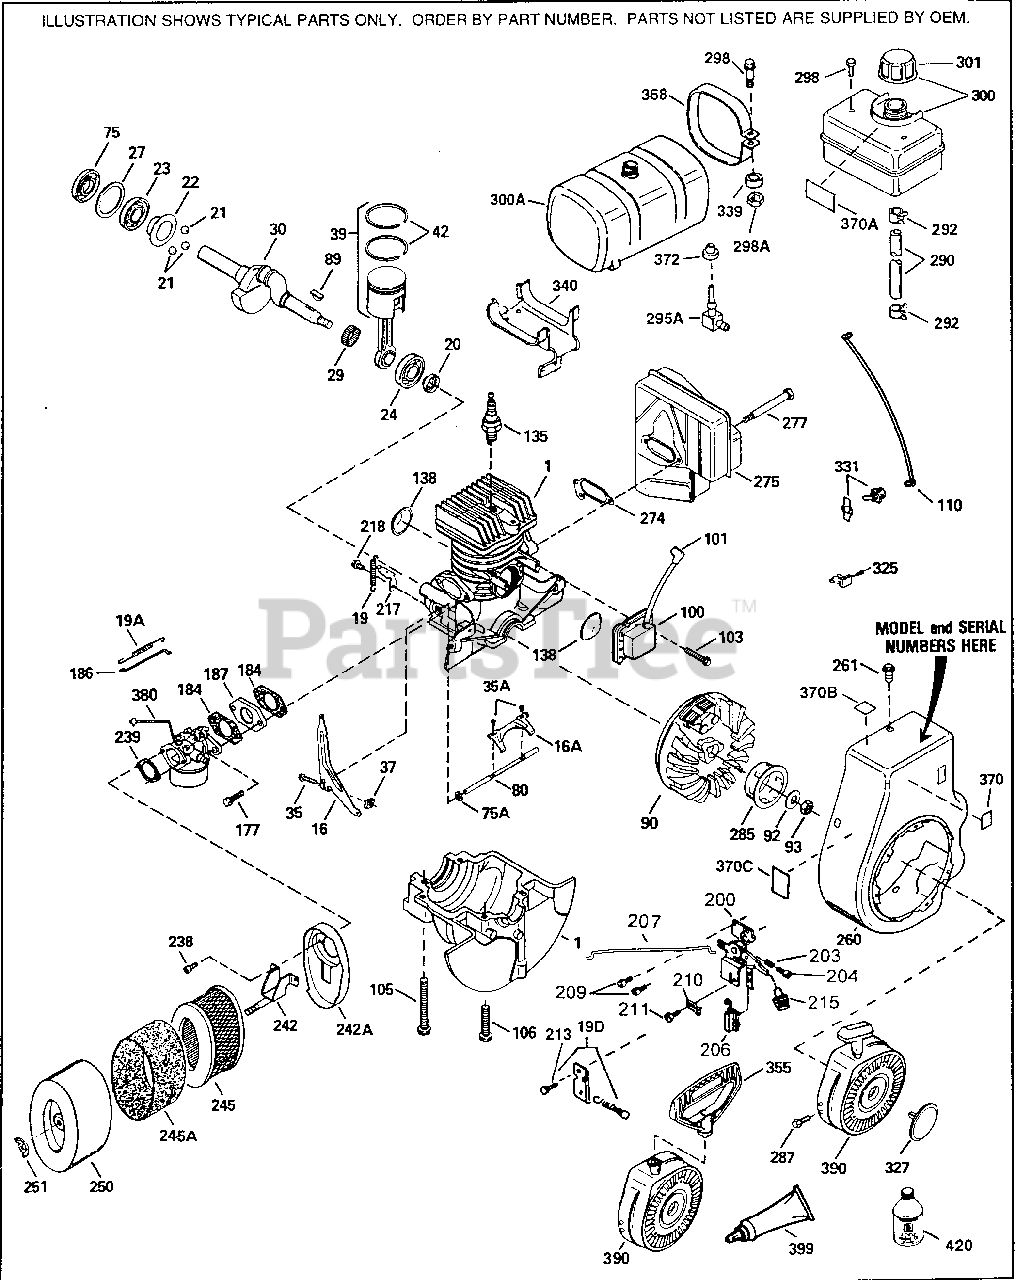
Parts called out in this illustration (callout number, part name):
1	"CYLINDER
16	Governor Lever
16A	Governor Follower Arm
19	Speed Control Spring
19A	Backlash Spring
19D	Extension Spring Ass'y. (Incl. 213)
20	Oil Seal
21	Ball Bearing
22	Slide Ring
23	Ball Bearing
24	Ball Bearing
27	Bearing Retainer
29	Bearing Strip (31 Needles)
30	Crankshaft
35	Screw, 10-32 x 3/4"
35A	Screw, 4-40 x 1/4"
37	Lock Nut, 10-32
39	Piston & Rod Ass'y. (Incl. 29 & 42)
42	Ring Set
75	Oil Seal
75A	Oil Seal
80	Governor Shaft
89	Flywheel Key
90	Flywheel
92	Belleville Washer
93	Flywheel Nut
100	Solid State Ignition
101	Spark Plug Cover
103	Screw, Torx T-15, 10-24 x 1"
105	Screw, 5/16-18 x 2-3/16"
106	Screw, 5/16-18 x 1-5/8"
110	Ground Wire
135	Resistor Spark Plug (RCJ8Y)
138	Port Cover
177	Screw, 5/32 Allen, 1/4-20 x 1"
184	Carburetor Gasket
186	Governor Link
200	Control Bracket Incl. 19D, 203, 204,& 213
203	Compression Spring
204	Screw, 5-40 x 7/16"
207	Throttle Link
209	Screw, 10-32 x 1/2"
210	Conduit Clip
211	Screw, 10-32 x 1/4"
213	Screw, 10-32 x 3/8"
238	Screw, 10-32 x 1/2"
239	Air Filter Gasket
242	Air Cleaner Bracket
242A	Air Cleaner Bracket Base
245	Air Filter (Paper) also available in Packaged Part #740027B
245A	Poly Pre-Filter (also available in Pa ckaged Part #740027B)
250	Air Cleaner Cover
251	Wing Nut, 1/4-20
260	Blower Housing
261	Screw, 5/16-18 x 5/8"
274	Exhaust Gasket
275	Muffler
277	Screw, 5/16-18 x 3-13/64"
285	Starter Cup
287	Screw, 8-32 x 21/64"
290	Fuel Line (8.62")
292	Fuel Line Clamp
295A	Fuel Fitting
298	Screw, 1/4-20 x 1-19/32"
300	Fuel Tank
301	Fuel Cap
325	Wire Clip
327	Starter Plug
340	Fuel Tank Bracket
368	Fuel Tank Strap
370	Name Decal
370A	Caution Decal
370B	Fuel Mix Decal
372	Bushing
380	Carburetor (Incl. 184)
390	Rewind Starter
399	Gasket Eliminator (Loctite 515)
420	2-Cycle Oil with Fuel Stabilizer - 8 oz.
